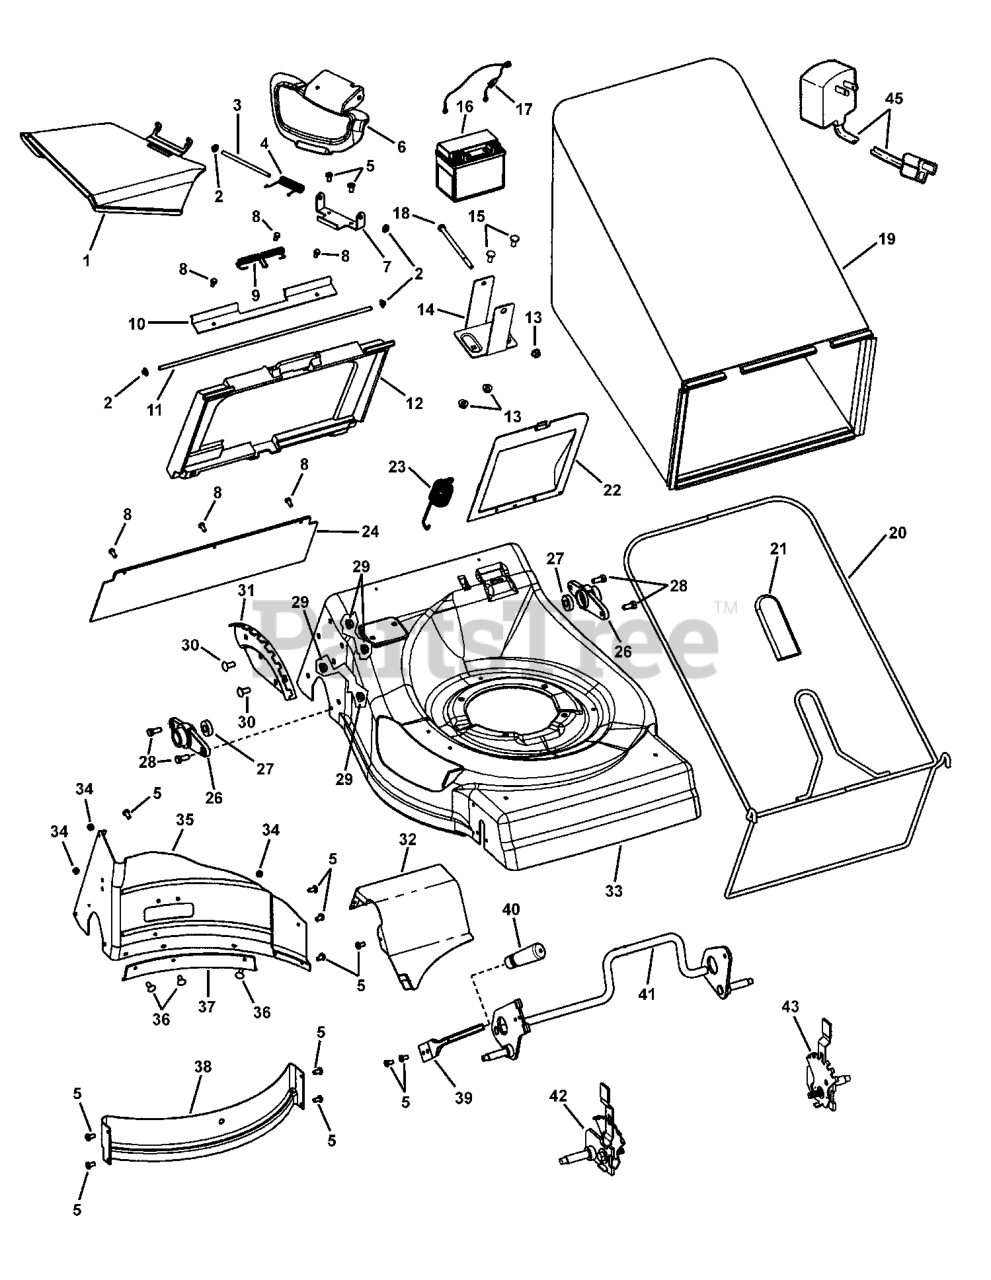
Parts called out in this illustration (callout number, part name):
1	CHUTE, 21" SIDE DISCHARGE
2	PUSHNUT 1/4
3	ROD, MULCH COVER PIVOT
4	SPRING, TORSION, CHUTE
5	TORX ST, 1/4-20 X 11/16
6	COVER, 21" MULCHING
7	BRACKET, CHUTE DEFLECTOR
8	HWST, 10-24X.50 SEMS
9	SPRING, TORSION
10	SPACER, REAR DOOR 21"
11	ROD, REAR DOOR PIVOT, 21" RD
12	DOOR, 21" BLACK
13	NUT, HEX FLANGE, 1/4-20, ESNA, YZ
14	BRACKET, BATTERY, 22" WBM ES
15	BOLT, 1/4-20X5/8
16	BATTERY KIT, Sealed Lead Acid 12V
17	HARNESS, BATTERY
18	HHCS, 1/4-20 x 4" GR 5
19	GRASSBAG, 21" RD
20	BAG FRAME - 21" RD WBM
21	GRIP, RECTANGULAR (BLACK)
22	TRANSMISSION COVER, REAR 21"
23	SPRING, EXTENSION, HOC ASSIST
24	DEFLECTOR, REAR, 21" WBM, RD
26	BEARING HOLDER, 21" WBM, RD
27	BEARING, Ball
28	CAPSCREW, 5/16 X 3/4 GR5 YZ
29	FLANGE NUT, 5/16-18 YZ
30	BOLT, 5/16-18 X 3/4 GR5 YZ
31	PLATE, HEIGHT OF CUT, INDEX, 7 POS, RD
32	BAFFLE, RIGHT REAR, 21" WBM, RD
33	DECK, 21" BRUTE, RD
34	NUT, 10-24 UNC-2B W/NYLON INSERT
35	BAFFLE, LEFT REAR, 21"RD,WBM
36	BOLT, 10-24 X 5/8 YZ
37	BAFFLE, EXTENSION, 21" RD WBM
38	BAFFLE, FRONT 21" WBM, RD
39	LEVER, SPRING HOC
40	GRIP, HEIGHT OF CUT
41	WELDMENT, REAR CROSSBAR 21" WBM, RD
42	HEIGHT OF CUT ASSEMBLY, RF, 7 POSITION
43	HEIGHT OF CUT ASSEMBLY, LF, 7 POSITION
45	CHARGER, BATTERY 120V/12V
